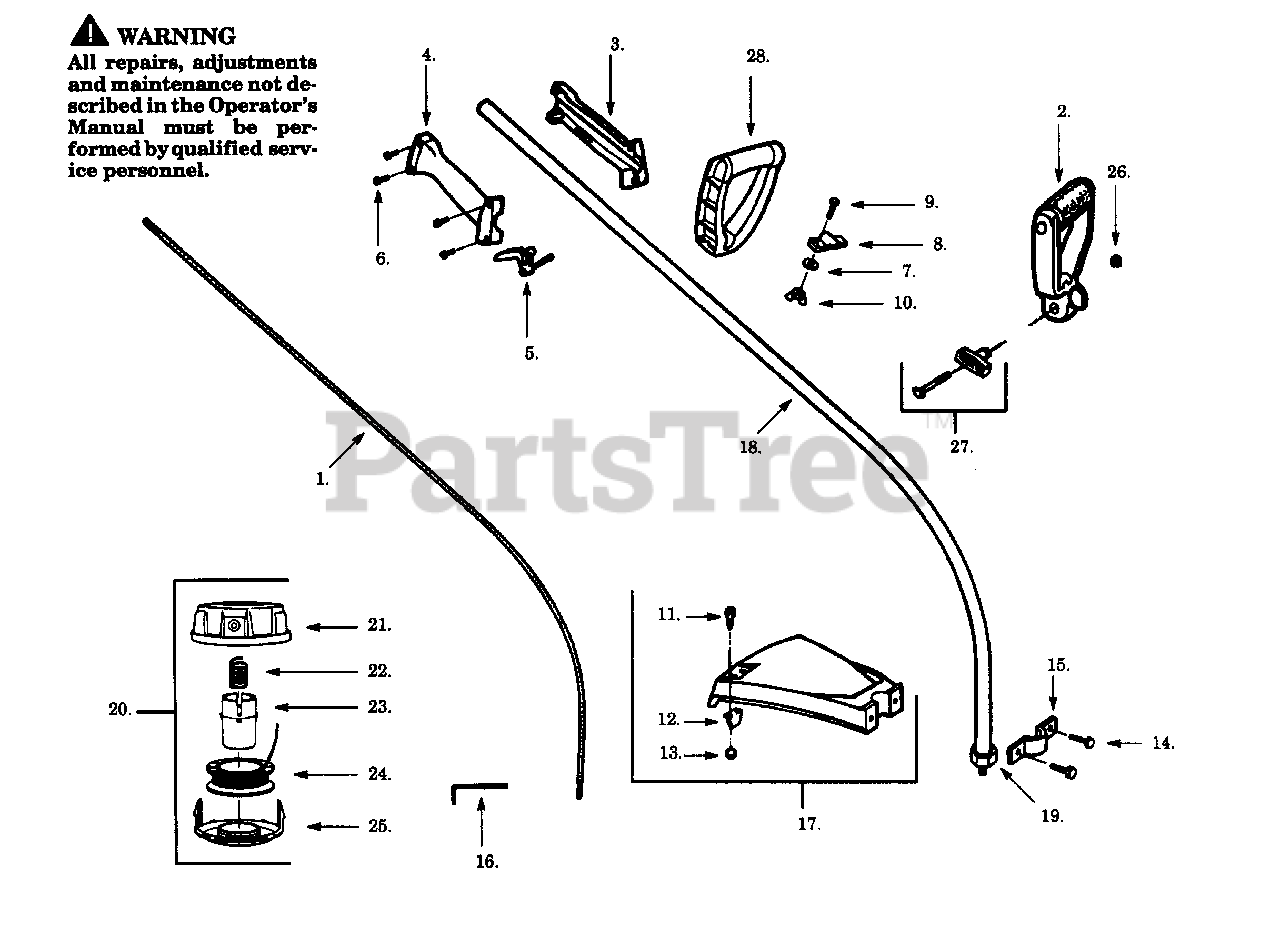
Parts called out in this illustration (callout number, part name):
1	Drive Shaft
3	Throttle Hsg. (Left)
4	Throttle Hsg. (Right)
5	Throttle Lever
6	Screw-throttle Housing
7	Washer-Handle
8	Clamp-Handle
9	Bolt-Handle
10	Wing Nut-Handle
11	Screw-Line Limiter
12	Line Limiter
13	Locknut-Line
14	Screw-Shield
15	Bracket Shield
16	Hex Wrench (5/32)
17	Shield Kit Ass'y.
18	Drive Shaft Hsg., LT7000
18	Drive Shaft Hsg., LT17
19	Dust Cup
20	Cutting Head Ass'y.
21	Hub Ass'y.
23	Release Button
24	Spool w/Line
26	Nut-Handle
27	"T" Handle Ass'y.
28	IIandle
